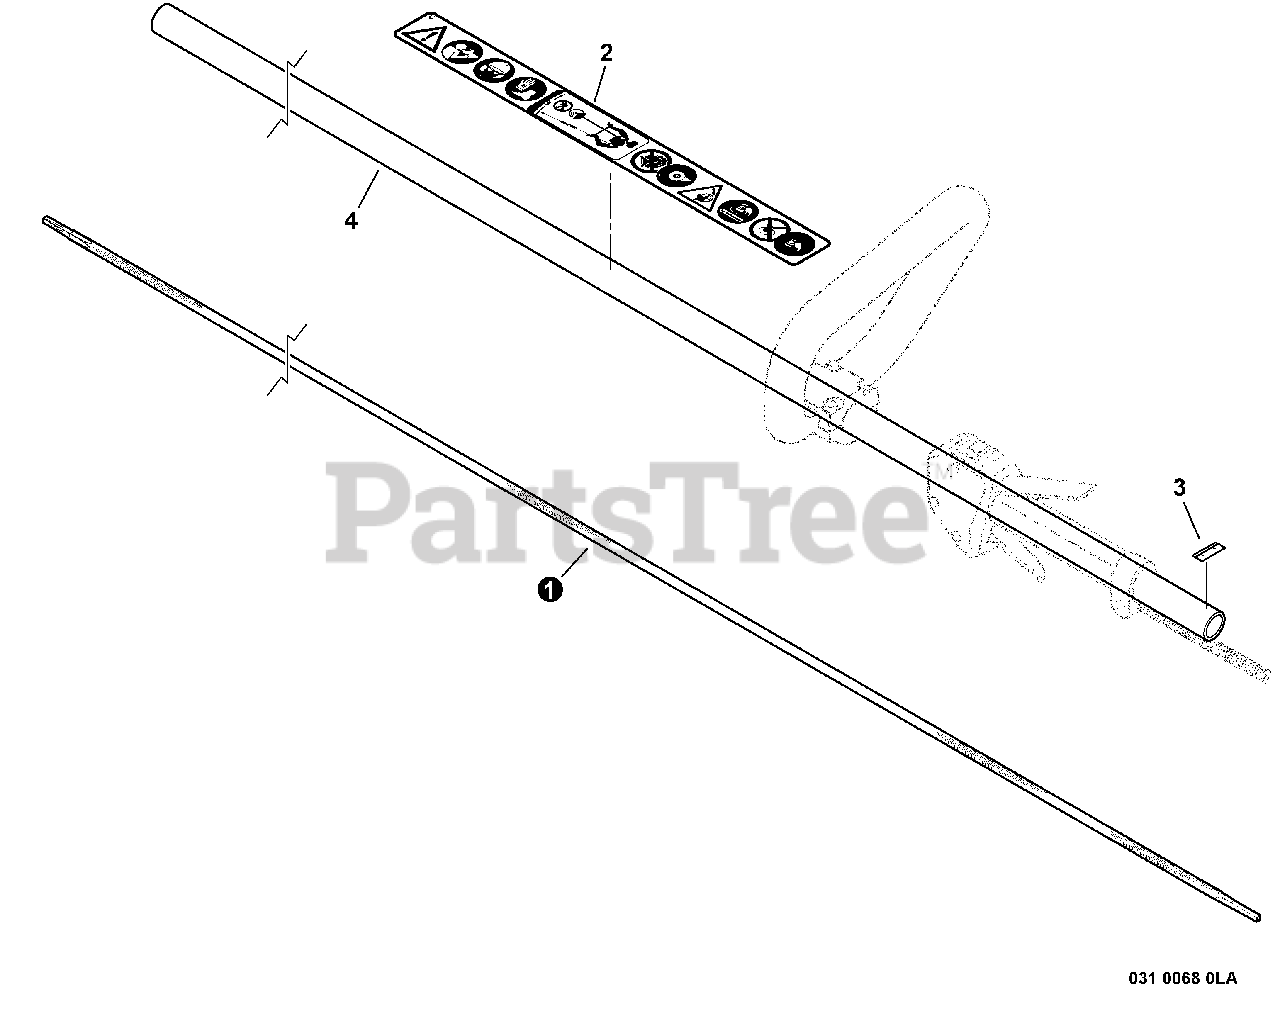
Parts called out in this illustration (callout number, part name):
1	DRIVESHAFT - FLEXIBLE
2	LABEL - CAUTION
3	LABEL - ALIGNMENT
4	MAIN PIPE ASSY
